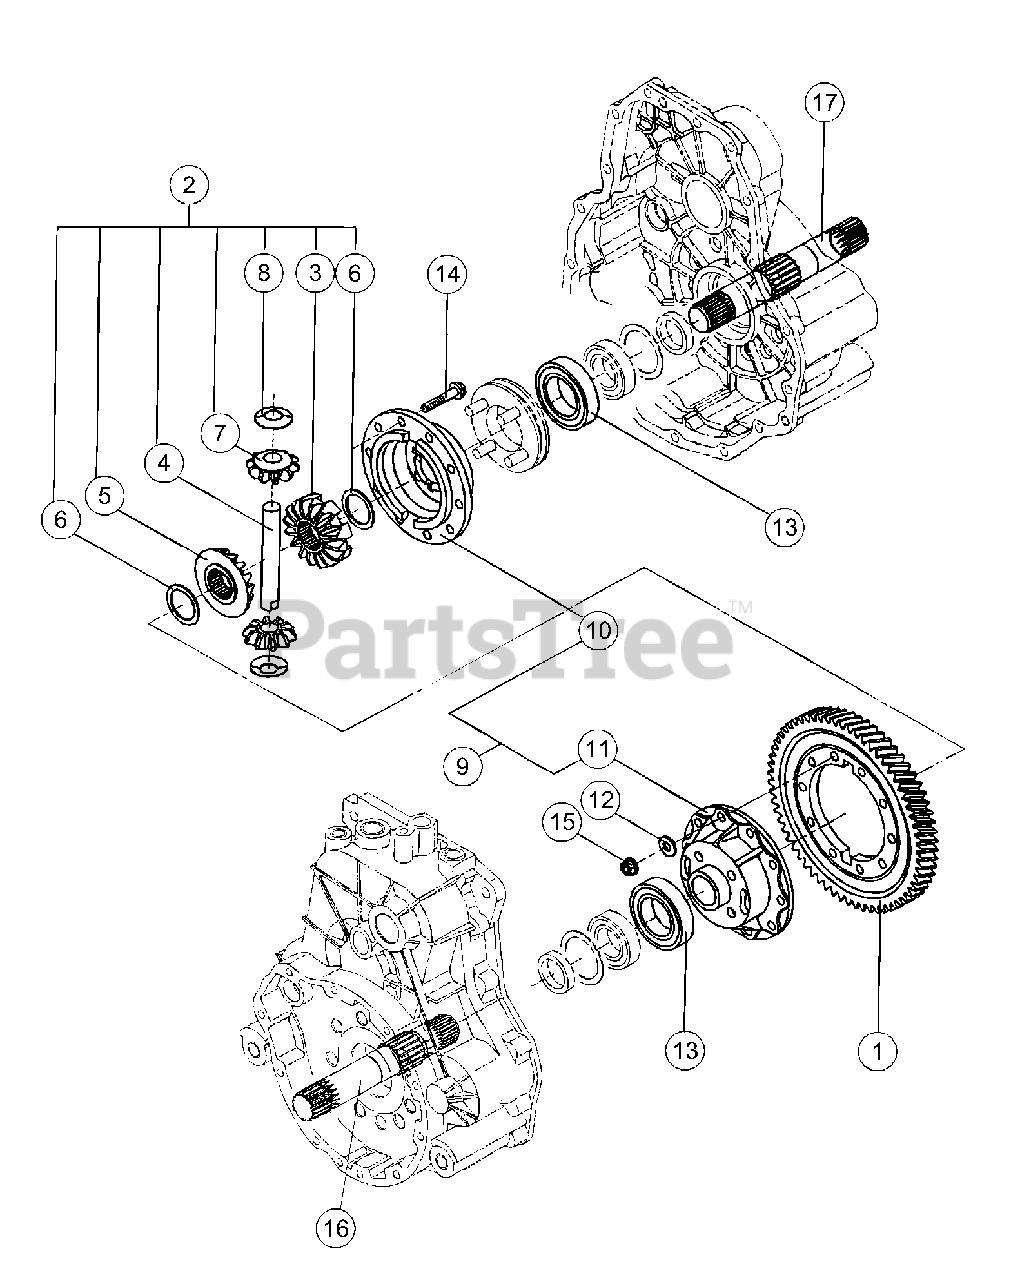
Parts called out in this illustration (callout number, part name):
1	Gear, 63H, Final
2	Differential, Gear Kit
3	Gear (RR, Differential)
4	Shaft, Differential Pinion
5	Differential Side Gear, RH
6	Washer, Differential Gear
7	Pinion, Differential
8	Washer, Differential Pinion
9	Differential, Case Kit
10	Case (R, Differential)
11	Case (L, Differential)
12	Washer, 8
13	Bearing, 6008
14	Bolt, 8 x 40
15	Nut, 8
